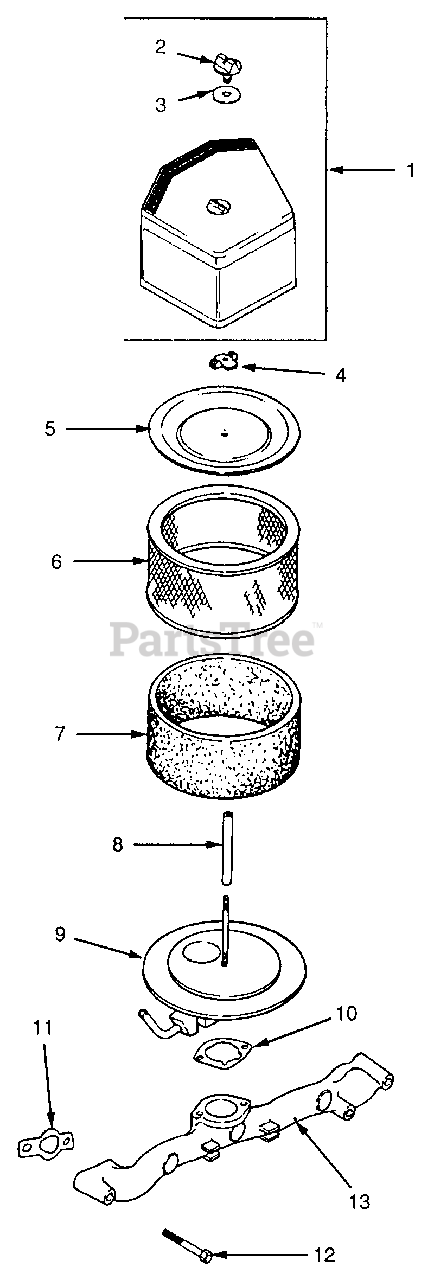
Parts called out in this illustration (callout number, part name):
1	Kit, Air Cleaner Cover
3	Gasket, Air Cleaner Cover Knob
5	Cover, Air Cleaner Element
6	Element, Air Cleaner
7	Precleaner, Element
9	Elbow, Air Cleaner
10	Gasket, Air Cleaner Base
11	Gasket, Intake Manifold
12	Screw, Hex Flange, M6 x 1.0 x 55
13	Manifold, Intake
